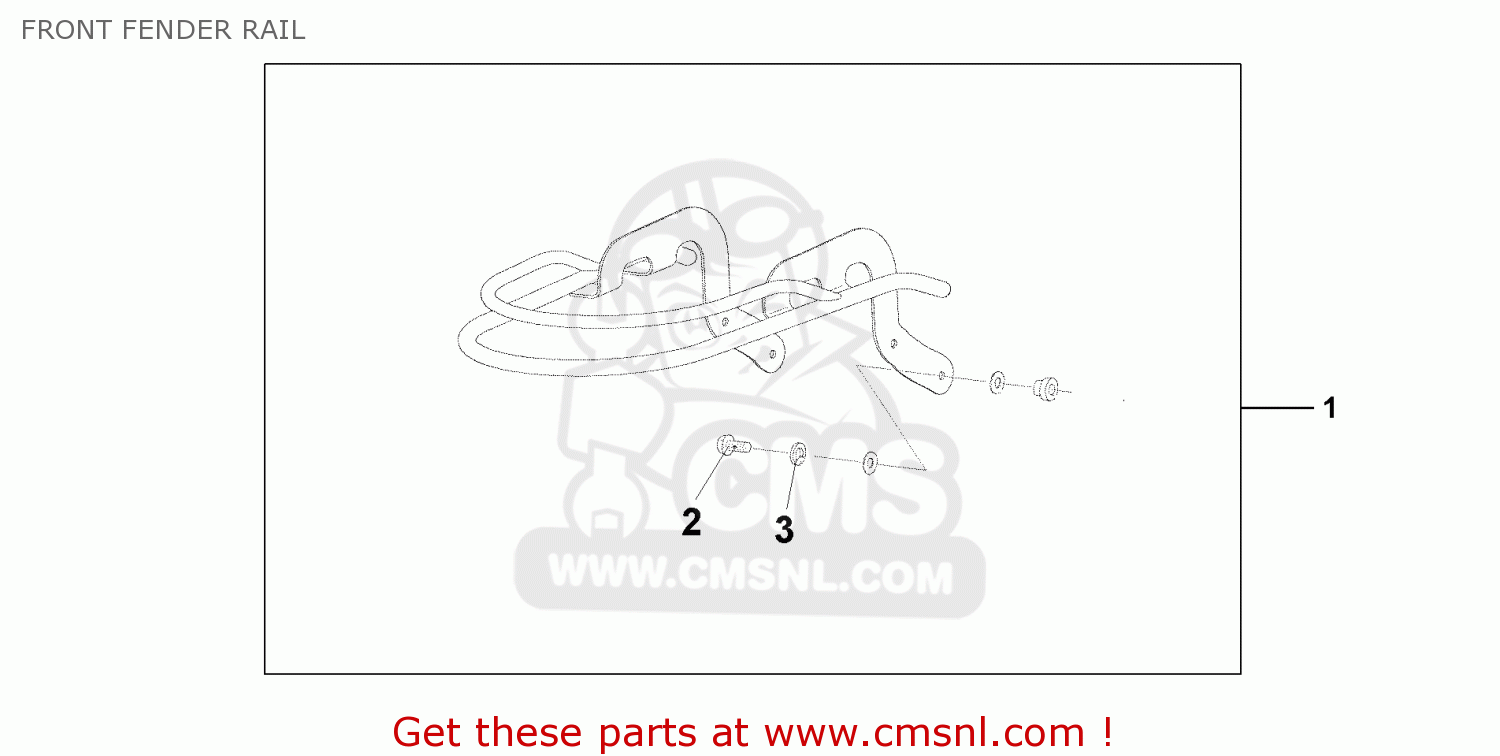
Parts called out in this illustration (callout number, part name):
1	FRONT MUDGUARD RAIL
2	BOLT,FLANGE,8X30
3	WASHER,PLAIN,12MM
